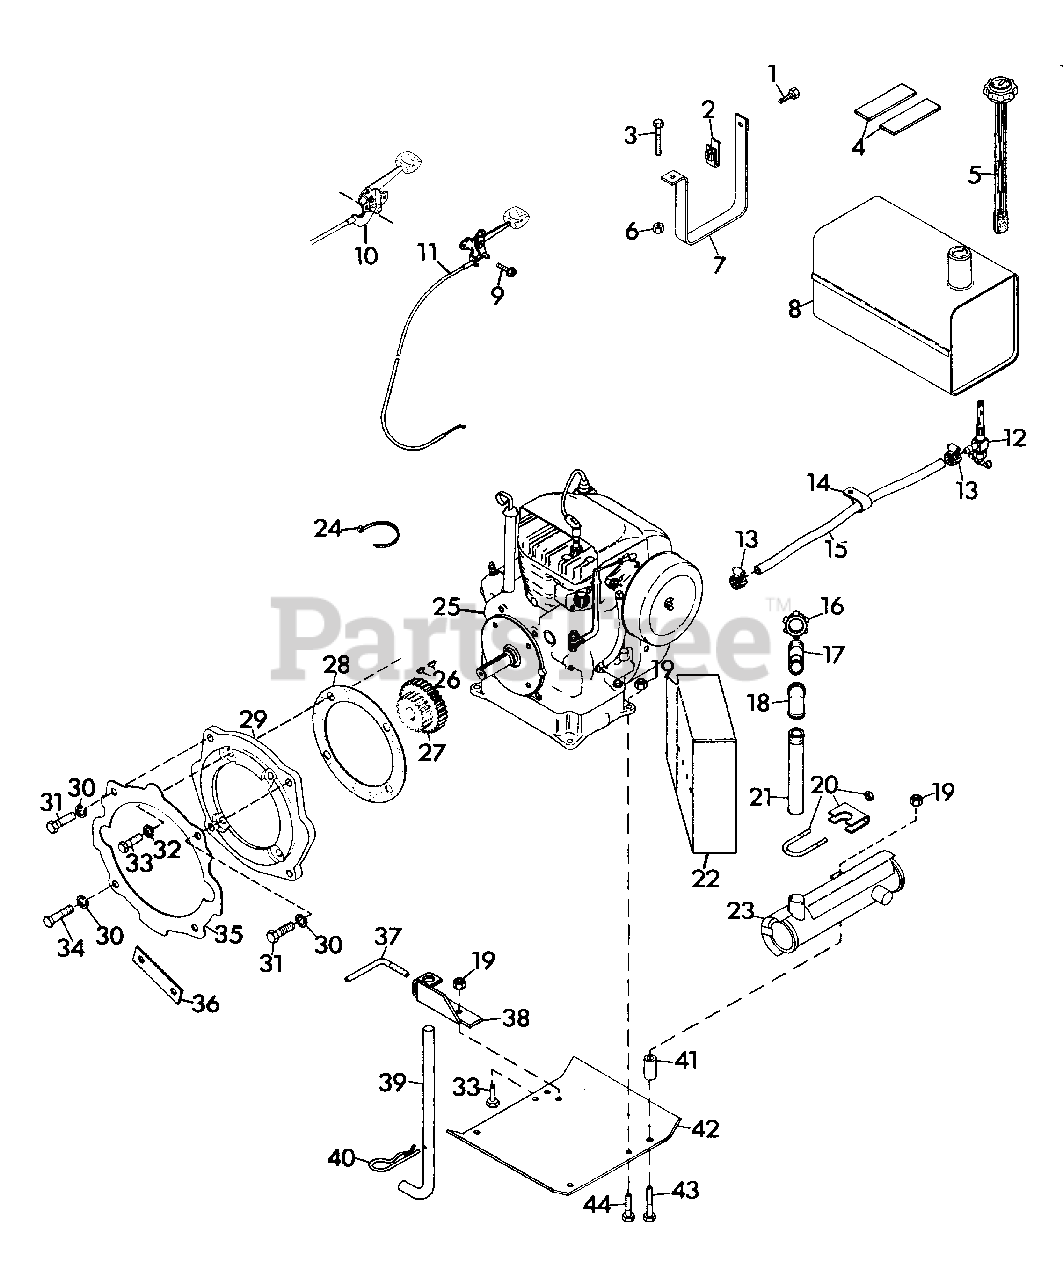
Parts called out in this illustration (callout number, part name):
1	BOLT, HEX 5/16-18X.75
2	NUT, RETAINER
3	BOLT, HEX 5/16-18X1.25
4	PAD, GAS TANK
5	GAUGE, FUEL
6	NUT, LOCK 5/16-18
7	STRAP, GAS TANK
8	TANK, FUEL
9	SCREW, TAPPING 10-24X.50
10	LEVER, THROTTLE
11	CONTROL, CHOKE
12	VALVE AND STRAINER
13	CLAMP, HOSE
14	CLAMP, NYLON
15	LINE, FUEL
16	NUT, CONDUIT 1.25" PIPE
17	NIPPLE, 1.25 PIPE
18	ELBOW, 1.25 PIPE
19	NUT, LOCK 3/8-16
20	CLAMP, MUFFLER
21	NIPPLE, 1.25 PIPE 7.8 LG
22	SHIELD, HEAT
23	MUFFLER, KOHLER 16-HP
24	TIE, CABLE
25	ENGINE, 16-HP MAGNUM
26	KEY, WOODRUFF 5/32X.625
27	GEAR, 10/12 DP 21/30 TEETH
28	GASKET, ENGINE TO ADAPTOR
29	ADAPTOR, ENGINE
30	WASHER, LOCK 7/16 SP HEAVY
31	BOLT, HEX 7/16-14X1.50
32	WASHER, LOCK 3/8 SP HEAVY
33	BOLT, HEX 3/8-16X1.00
34	BOLT, HEX 7/16-14X1.25
35	GASKET, CHASSIS TO ADAPTOR
36	STRAP
37	HANDLE, ADJUSTING
38	STAND, SUPPORT
39	STAND, KICK
40	PIN, HAIR
41	BUSHING, .407X.625X.812
42	PLATE, SKID
43	BOLT, HEX 3/8-16X1.75
44	BOLT, HEX 3/8-16X1.50
